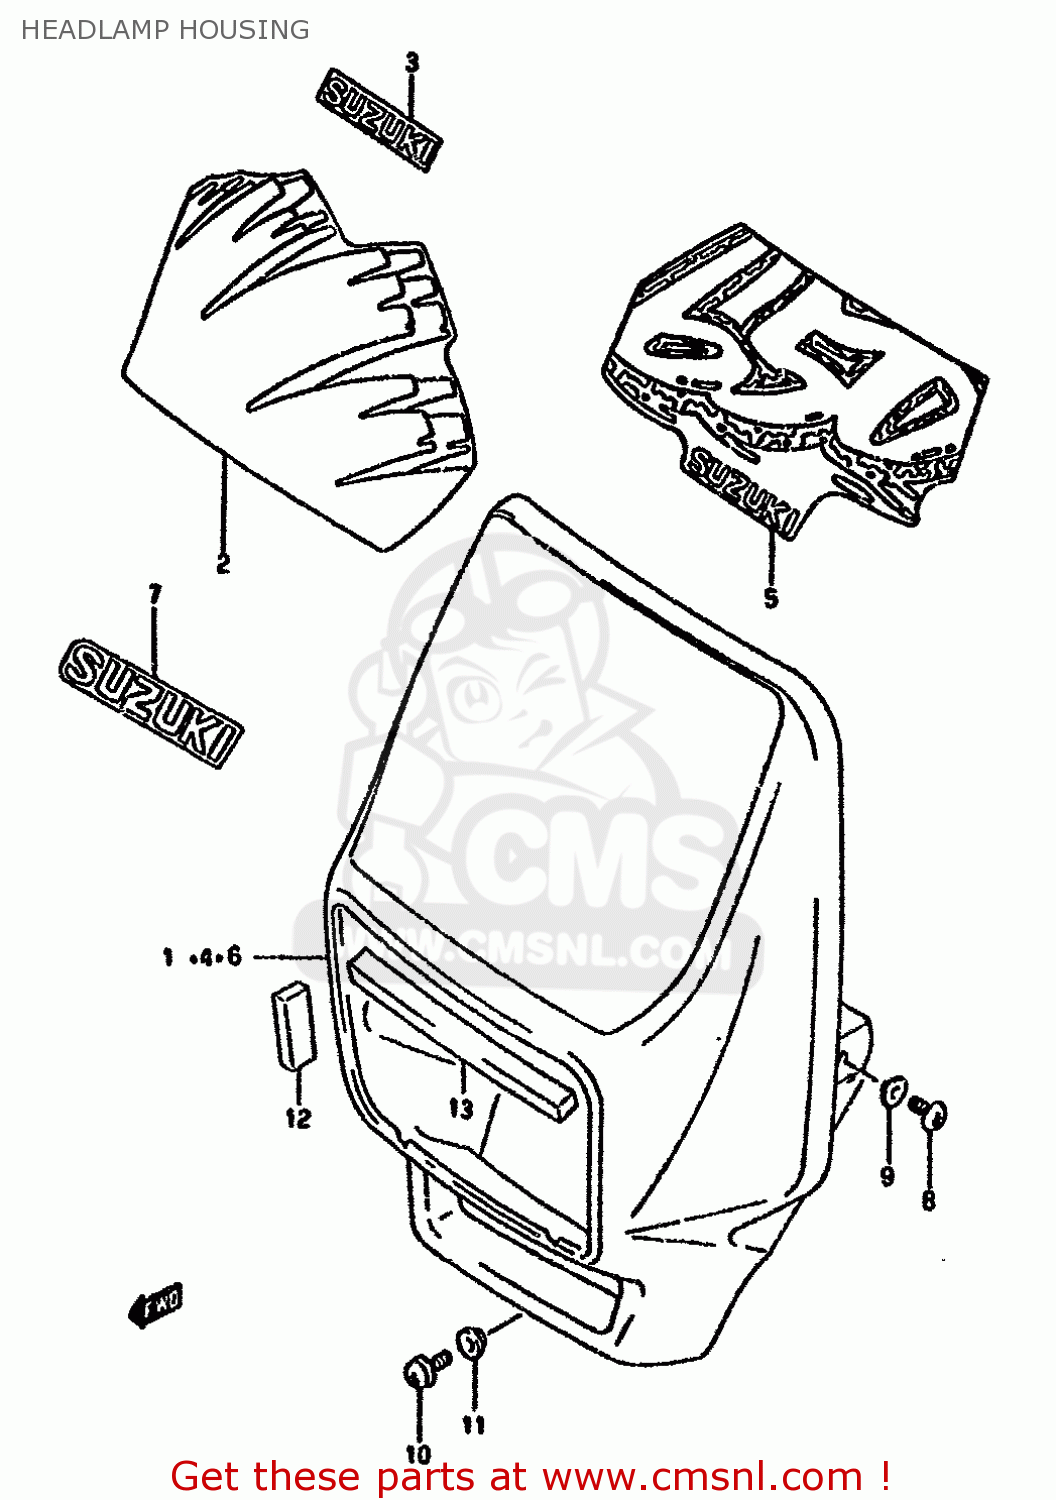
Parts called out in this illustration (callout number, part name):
1	COVER ASSY,HEADLAMP (WHITE)
2	TAPE,HEADLAMP COVER
3	EMBLEM,HEADLAMP COVER
4	HOUSING ASSEMBLY,HEADLAMP
5	TAPE,HEADLAMP COVER
6	HOUSING ASSEMBLY,HEADLAMP
7	EMBLEM, SUZUKI
8	SCREW 6X12
9	WASHER
10	SCREW
11	WASHER(5.2X14X1.5)
12	CUSHION,HEADLAMP COVER
13	CUSHION,HEADLAMP COVER SIDE
